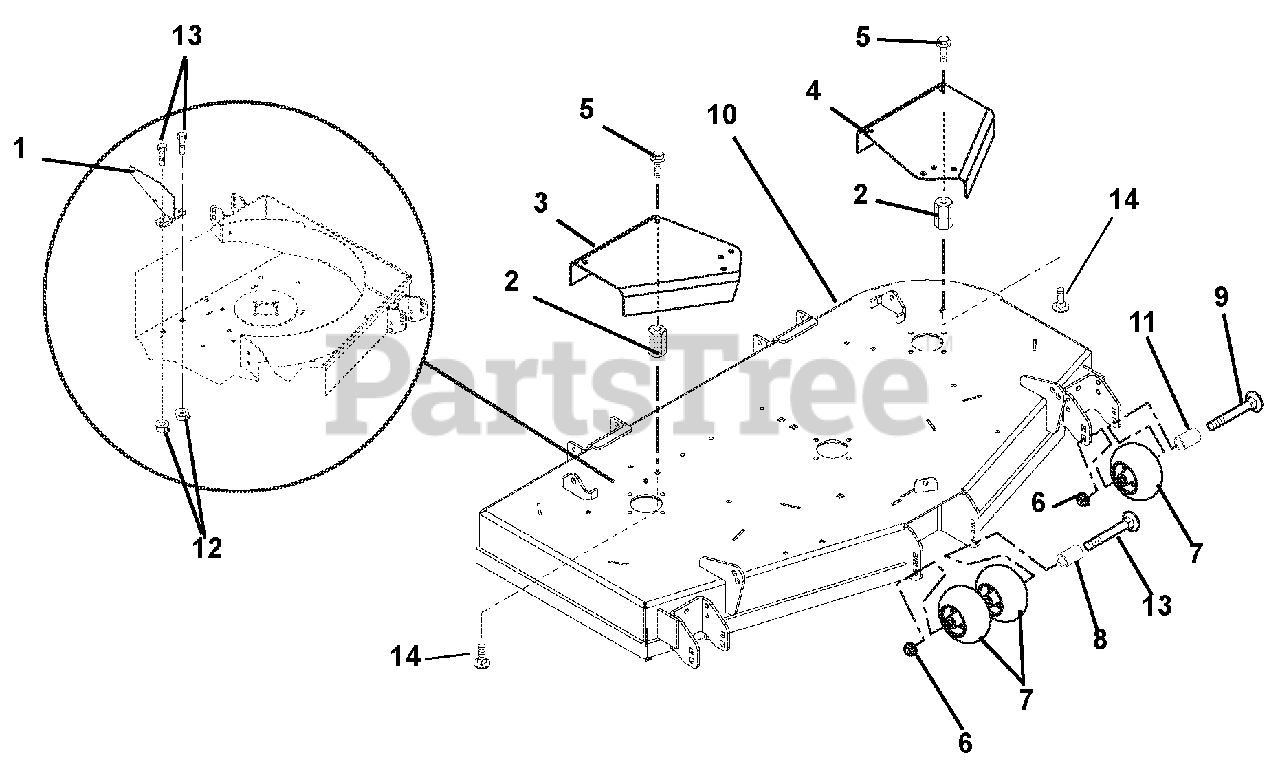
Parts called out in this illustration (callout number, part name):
1	REAR DISCH DEFLECT BFL WMT-RED
2	NUT, COUPLING .31-18 X 3.00
3	GUARD,52"RH SPINDLE SHEAVE 200
3	60"RH SPINDLE SHEAVE GUARD-RED
3	72"RH SPINDLE SHEAVE GUARD-RED
4	44"-52" LH SPNDL SHV GUARD-RED
4	60"LH SPINDLE SHEAVE GUARD-RED
4	72"LH SPINDLE SHEAVE GUARD-RED
5	BOLT, SEMS .31-18 X .62
6	@NUT-LK-NYL-FLG .50-13 YWZC
7	WHEEL, ANTI SCALP
8	SPACER, .510X.625X6.50
9	BLT-RDHDSQNK .50-13X5.00 GR5YZ
10	XDZ52" REAR DISCH DECK WMT-RED
10	XDZ60" REAR DISCH DECK WMT-RED
10	72"XDZ REAR DISCH DECK WMT-RED
11	SPACER, .510X.625X3.35
12	@NUT-LK-NYL-FLG .38-16 YWZC
13	@BLT-RDHDSHSQNK.38-16X1.0 G5YZ
14	BLT,RDHDSQNK .31-18X.75 LOCTIT
